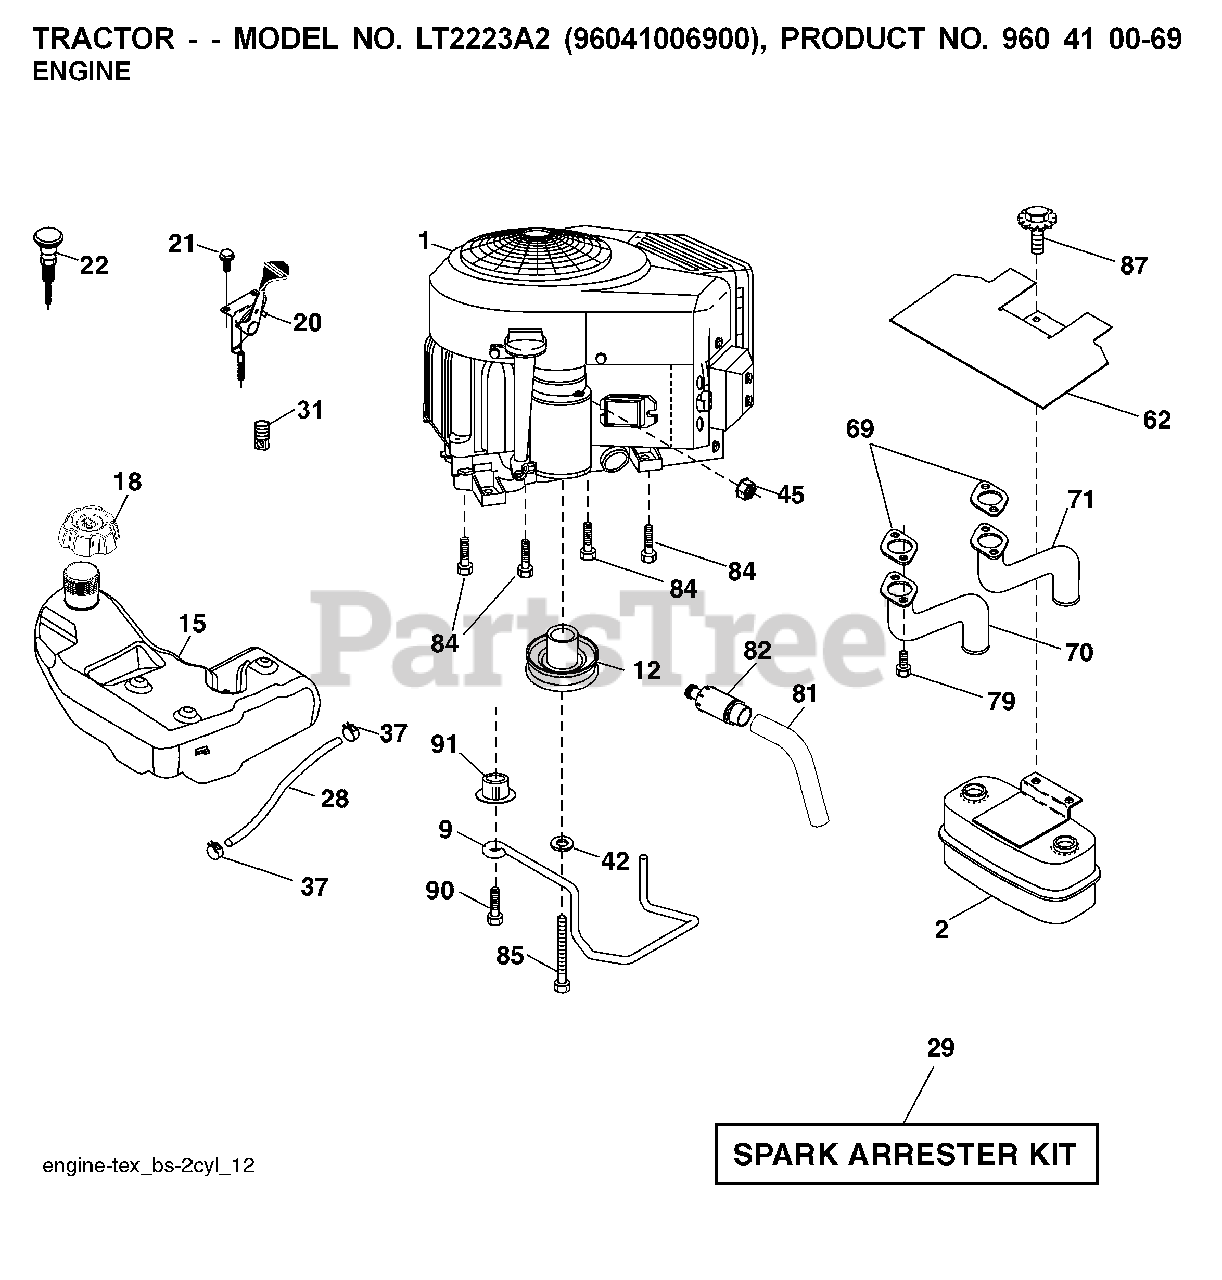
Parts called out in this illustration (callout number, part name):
2	MUFFLER.TWIN.CYL.LOW.TONE
9	KEEPER.BELT.ENGINE.4.2
12	PULLY ENGINE
15	TANK.FUEL.SIDE-FILL.3.NON-EPA
18	CAP.ASM.FUEL.TANK.3"BL
20	THROTTLE CABLE
21	SCREW.#10 X 0.750.BOS THREAD
22	CONTROL CHOKE
29	ARRESTER SPARK (OPTIONAL)
31	PUSH CLIP
37	HOSE CLAMP
42	LOCKWASHER
45	NUT
62	RP SHIELD HEAT MUFFLER
69	GASKET.MUFFLER
70	TUBE MANIFOLD LH
71	EXHAUST TUBE RH
79	SCREW.SOCKET.HEAD.5/16-18
81	TUBE, DRAIN OIL ASM.
82	PLUG DRAIN OIL EASY
84	SCREW.3/8-16
85	BOLT HEX 7/16-20X4-1/4"
87	BOLT, 5/16-18 X 1 3/4
90	SCREW 3/8-16X1
91	BUSHING.1.375OD
